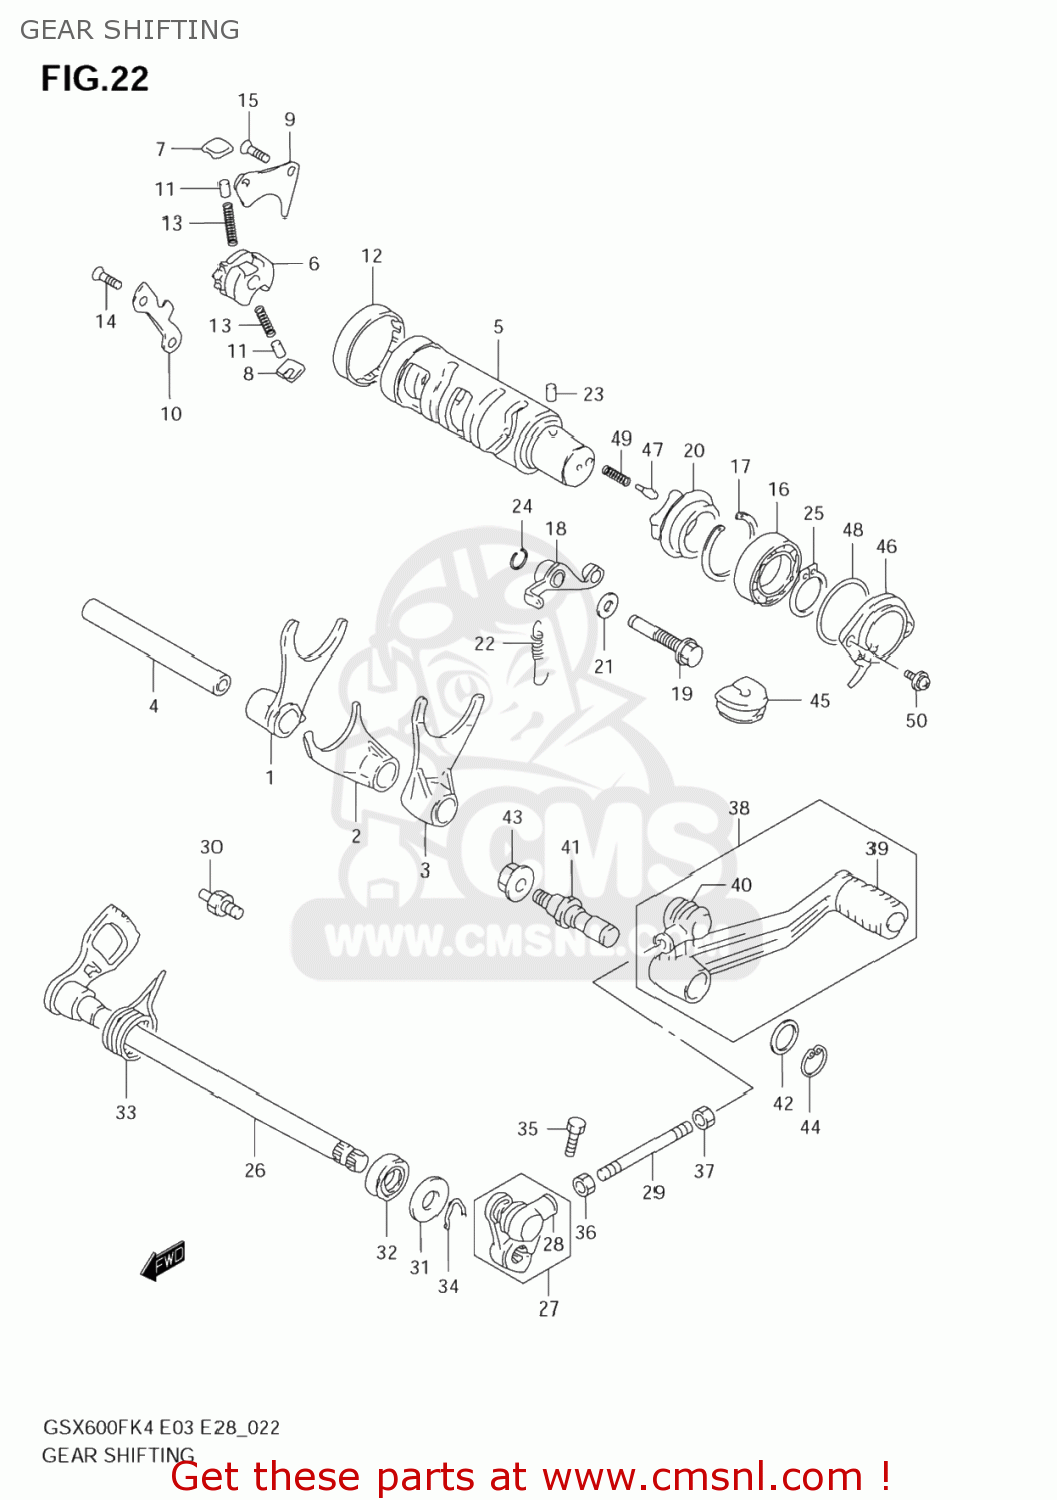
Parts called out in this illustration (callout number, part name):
1	FORK,GEAR SHIFT NO.1
2	FORK,GEAR SHIFT NO.2
3	FORK,GEAR SHIFT NO.3
4	SHAFT,GEAR SHIFT FORK(L:128)
5	CAM,GEAR SHIFT
6	GEAR,GEAR SHIFT CAM DRIVEN
7	PAWL,GEAR SHIFT NO.1
8	PAWL,GEAR SHIFT NO.2
9	LIFTER,GEAR SHIFT PAWL
10	GUIDE,GEAR SHIFT CAM
11	PIN(5X8)
12	BEARING(43X49X12)
13	SPRING
14	SCREW(6X12)
15	SCREW(6X12)
16	BEARING
17	CIRCLIP
18	STOPPER,GEAR SHIFT CAM
19	SHAFT,GEAR SHIFT CAM STOPPER
20	PLATE,STOPPER
21	GASKET(10X14X3.6) (NAS)
22	SPRING
23	PIN
24	CIRCLIP
25	CIRCLIP
26	SHAFT,GEAR SHIFT
27	ARM,GEAR SHIFT LINK
28	COVER,DUST
29	ROD,GEAR SHIFT LINK
30	STOPPER,GEAR SHIFT ARM
31	WASHER (12.5X26X1.6)
32	OIL SEAL
33	SPRING
34	CIRCLIP,12 MM
35	BOLT
36	NUT
37	NUT
38	LEVER ASSY,GEAR SHIFT
39	RUBBER,GEAR SHIFT PEDAL
40	COVER,DUST
41	SHAFT,GEAR SHIFT LEVER
42	WASHER(12.5X20X1)
43	NUT
44	CIRCLIP,12 MM
45	GROMMET,LEADWIRE
46	BASE ASSY,GEAR SHIFT TERMINAL
47	PIN(5X15.5)
48	O RING(D:2.4,ID:35.5)
49	SPRING
50	SCREW(5X16)
